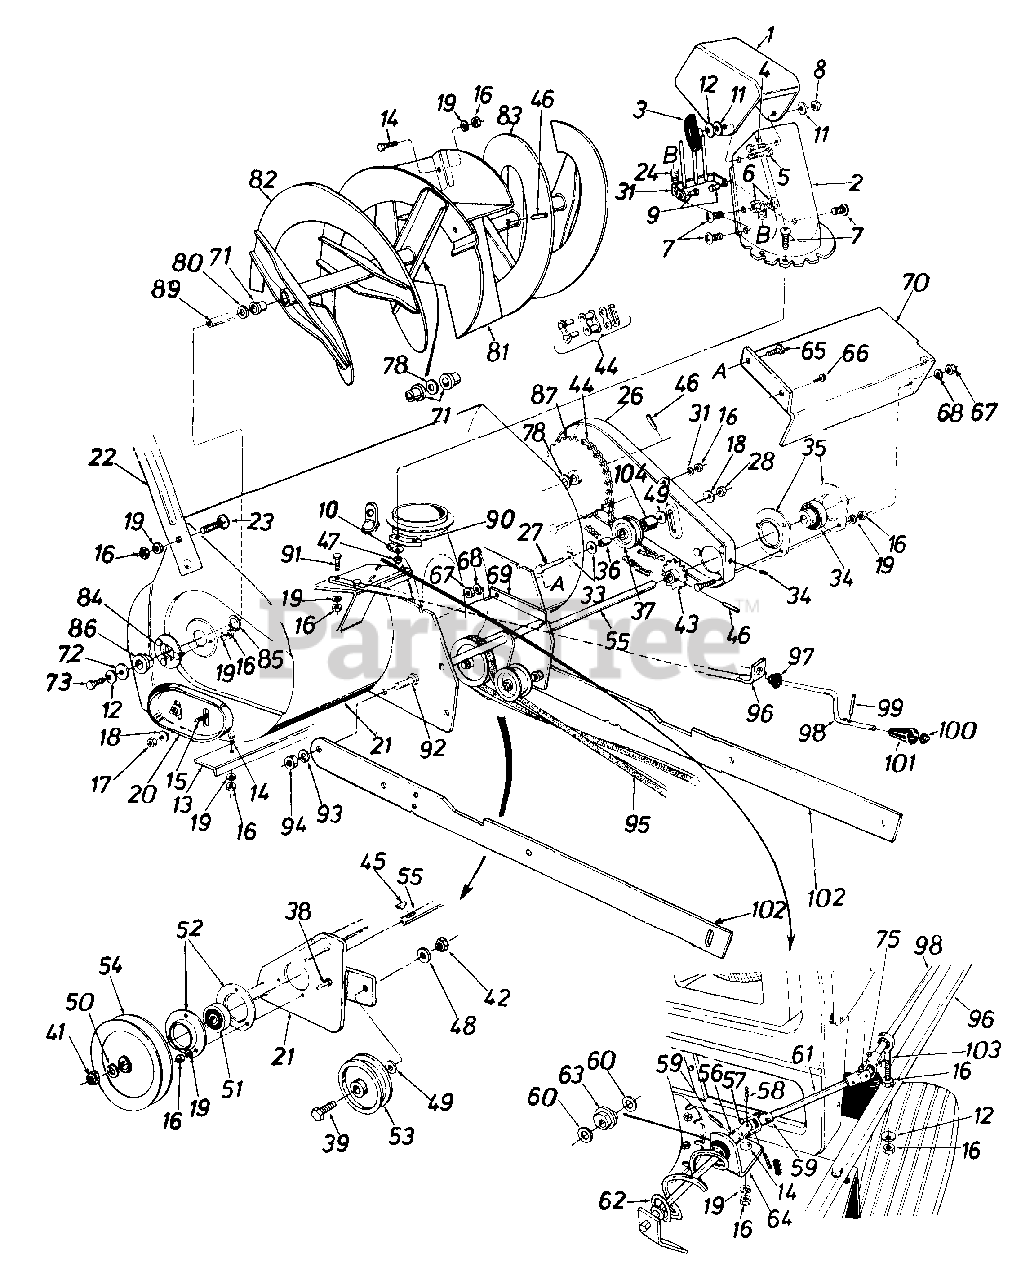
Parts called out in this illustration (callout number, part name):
1	Upper Chute
2	Lower Chute
3	Knob Handle Ass'y.
4	Truss Mach. Scr. 5/16-18 x .75" Lg.
5	Carriage Bolt 5/16-18 x 1" Lg.
6	Hex Cent. L-Nut 5/16-18 Thd.
7	Truss Mach. Scr. 1/4-20 x .75" Lg.
8	Hex Cent. L-Nut 5/16-18 Thd.
9	Shld. Nut 1/4-20 Thd.
10	Fl-Wash. 1/4" I.D.
11	Fl-Wash. .344" I.D. x 1.125"
12	Bell-Wash. .345" I.D. x .88"
14	Carriage Bolt 5/16-18 x .62" Lg.
15	Carriage Bolt 3/8-16 x .62" Lg.
16	Hex Nut 5/16-18 Thd.
17	Hex Jam Nut 3/8-16 Thd.
18	Bell-Wash. .40" I.D. x .88"
19	L-Wash. 5/16" I.D.
20	Slide Shoe
21	Spiral Hsg. Ass'y. - 36"
23	Carriage Bolt 5/16-18 x .62"
24	Extension Spring
26	Chain Guard Ass'y.
27	Hex Bolt 3/8-16 x 2" Lg.
28	Hex Ins. Nut 3/8-16 Thd.
33	Fl-Wash. .385" I.D. x .87" O.D.
34	Ball Brg. .75" I.D.
35	Flangette
36	Spacer .375" I.D. x .60" O.D.
37	Flat Idler 1.875" Dia.
38	Hex Sems Bolt 5/18 x .75" Lg.
39	Hex Bolt 3/8-16 x 1.75" Lg.
41	Hex Jam Nut 3/4-10 Thd.
42	Hex Jam Nut 3/8-16 Thd.
43	Sprocket Ass'y. - 14 Teeth
44	#420 Chain x 1/2" Pitch - 77 Links
45	#61 Hi-Pro-Key 3/16 x 5/8"
46	Spring Pin Spir. 5/16" Dia. x 1.75" Lg.
47	Hex L-Nut 1/4-20 Thd.
48	L-Wash. 3/8" I.D.
49	Fl-Wash. .406" I.D. x 1.25"
50	Spr. L-Wash. 3/4" I.D.
51	Self-Aligning Brg.
52	Flangette
53	Idler Pulley
54	5/8 V-Pulley .75" I.D. x 6" O.D.
55	Drive Shaft Ass'y.
56	Joint Brkt. Ass'y.
58	Oval Head Rivet
59	Spiral Pin 1/8" Dia.
60	Fl-Wash. .385" I.D. x .62"
61	Chute Crank Ext. Rod
62	Chute Crank Ass'y. R.H.
63	Plastic Bushing .38" I.D.
64	Chute Crank Brkt.
65	Hex Bolt 1/4-20 x .62" Lg.
66	Hex Wash. S-Tap Scr. 1/4-20 x .50" Lg.
67	Hex Nut 1/4-20 Thd.
68	L-Wash. 1/4" I.D.
70	Drive Shaft Cover
71	Plastic Bushing
72	Washer .39" I.D. x 1.75" O.D.
73	Hex Bolt 5/16-18 x .88" Spec.
75	Cotter Pin 3/32" Dia.
78	Fl-Wash. 1.03" I.D. x 1.62"
80	Fl-Wash. 1" I.D. x 1.75"
85	Snap Ring for 1.5" Shaft
86	Flange Brg. w/flats 1" I.D.
87	Sprocket Hub Ass'y. 40 Teeth
90	Chute Flange Keeper
91	Hex Bolt 5/16-18 x 1.5" Lg.
92	Hex Bolt 1/2-13 x 1.25" Lg.
93	L-Wash. 1/2" I.D.
94	Hex Nut 1/2-13 Thd.
95	"V"-Belt
98	Chute Crank 34.5" Lg.
99	Roll Pin .12" Dia. x .63"
100	Push Nut 3/8" Rod
102	Linkage Arm
103	Eye Bolt 5/16-18 x 3" Lg.
104	Idler Spacer
05139A-0637	BLADE-GUIDE (DRIFT - POWDER BLACK (0637)
05139A-0638	BLADE-GUIDE (DRIFT - MTD/TROY-BILT RED (0638)
05139A-0662	BLADE-GUIDE (DRIFT - OYSTER GRAY (0662)
05139A-0665	BLADE-GUIDE (DRIFT - YARDMAN GREEN (0665)
05139A-0674	BLADE-GUIDE (DRIFT - YARDMAN YELLOW (0674)
05139A-0716	BLADE-GUIDE (DRIFT - CUB YELLOW-99 (0716)
